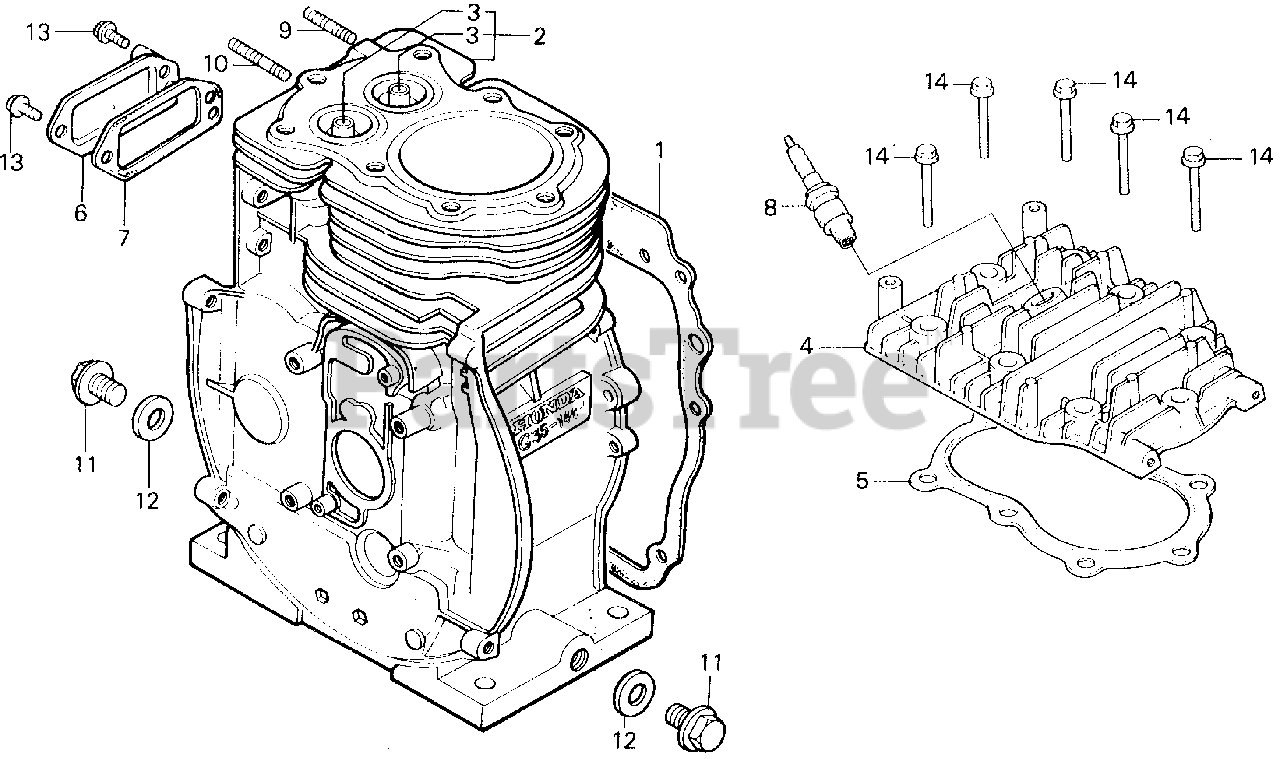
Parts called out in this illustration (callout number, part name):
1	GASKET, CRANKCASE COVER (NOT AVAILABLE)
3	GUIDE, VALVE (OS)
4	CYLINDER HEAD
5	GASKET, CYLINDER HEAD (NOT AVAILABLE)
6	COVER, TAPPET ROOM
7	GASKET, TAPPET COVER (NOT AVAILABLE)
8	SPARK PLUG (BR6HS) (NGK)
9	BOLT, STUD (6X28)
10	BOLT, STUD (6X37)
10	BOLT 2, STUD (6X25)
11	BOLT, DRAIN PLUG (12MM)
12	WASHER, DRAIN PLUG (12MM)
13	BOLT, FLANGE (6X12)
14	BOLT, FLANGE (8X40)
